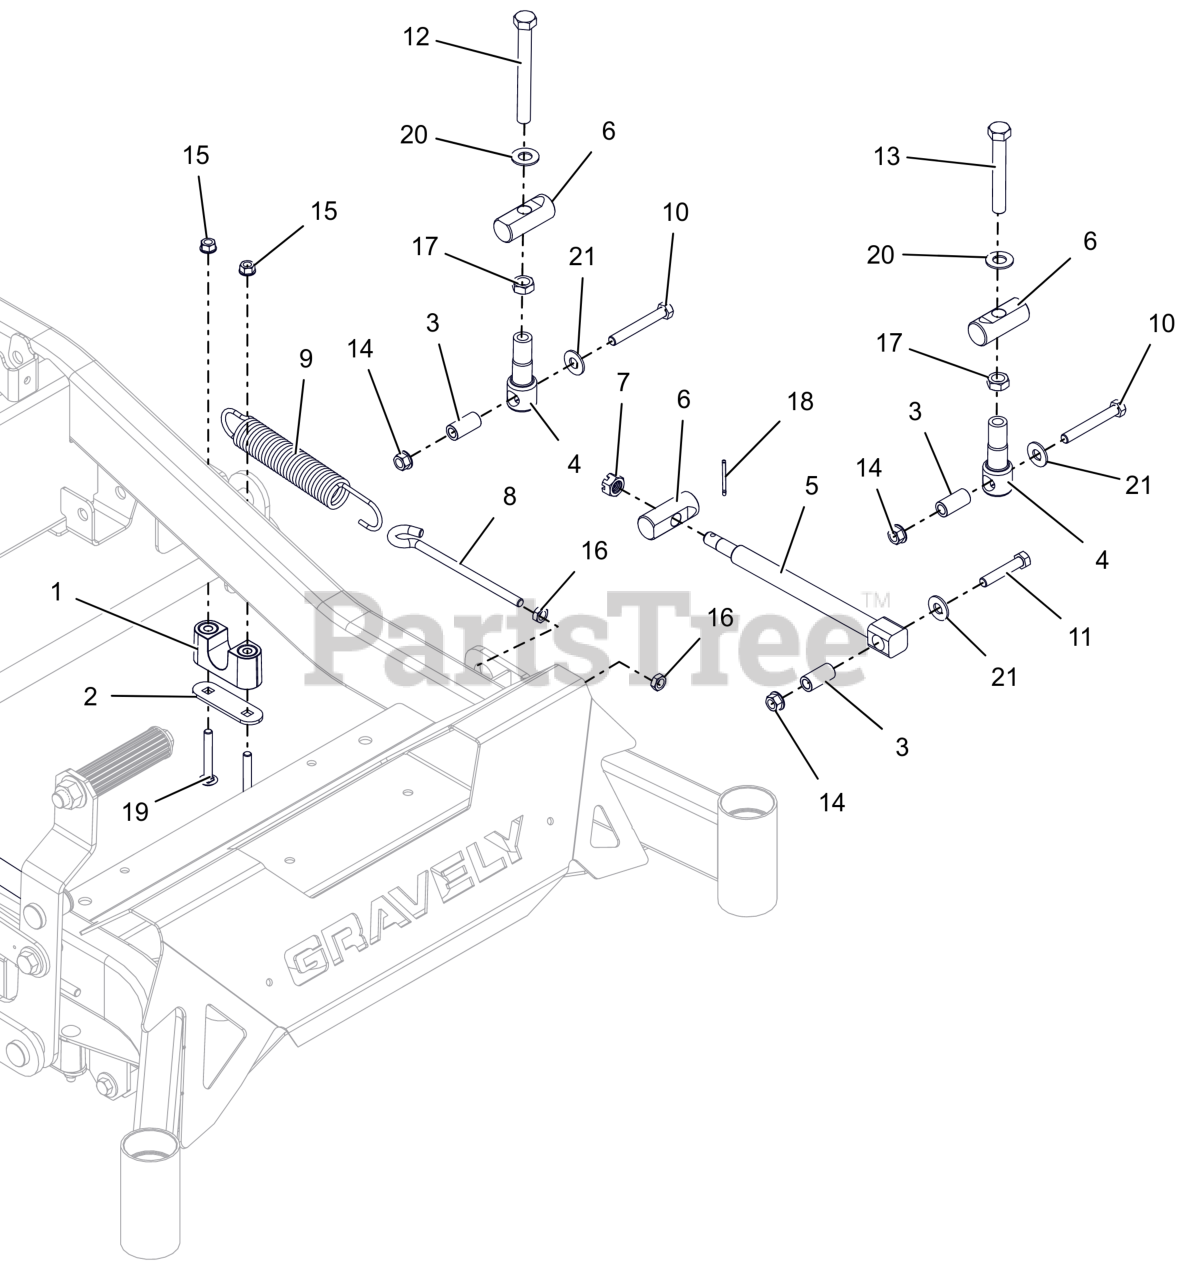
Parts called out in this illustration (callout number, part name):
1	ASM-BUSHING, DECK LIFT
2	PLATE, BEARING SUPPORT
3	SPACER, DECK LEVELING
4	LINK, DECK LIFT FORMED
5	DRAG,LINK-HD
6	PIN, DECK LIFT
7	NUT-SL .50-13
8	BOLT,.38-16 X 5.25-.62 DIA EYE
9	SG-TENS .162X1.25X8.25 WLD 25
10	BLT, HEX .38-16X2.75 G8 ZCC
11	BLT,HEX .38-16X2.00 G5 ZCC
12	BLT, HEX .50-13X4.50F G8 ZCC
13	BLT, HEX 0.5-13X3.5F GR5 ZCC
14	NUT-LK-TOP-FLG .38-16 ZC120
15	NUT,LK-CTR-FLG .31-18 GF ZCC
16	NUT-JAM .375-16 G2 ZCC
17	NUT-JAM .500-13 G2 ZCC
18	PIN,CTR.12X1.25EXTPRSQCT ZC120
19	BLT, RHSSN.31-18X2.25 G5 ZCC
20	WSHR, FLT .557X1.040X.102 ZCC
21	WSHR,FLT .438X1.00X.083 ZCC
